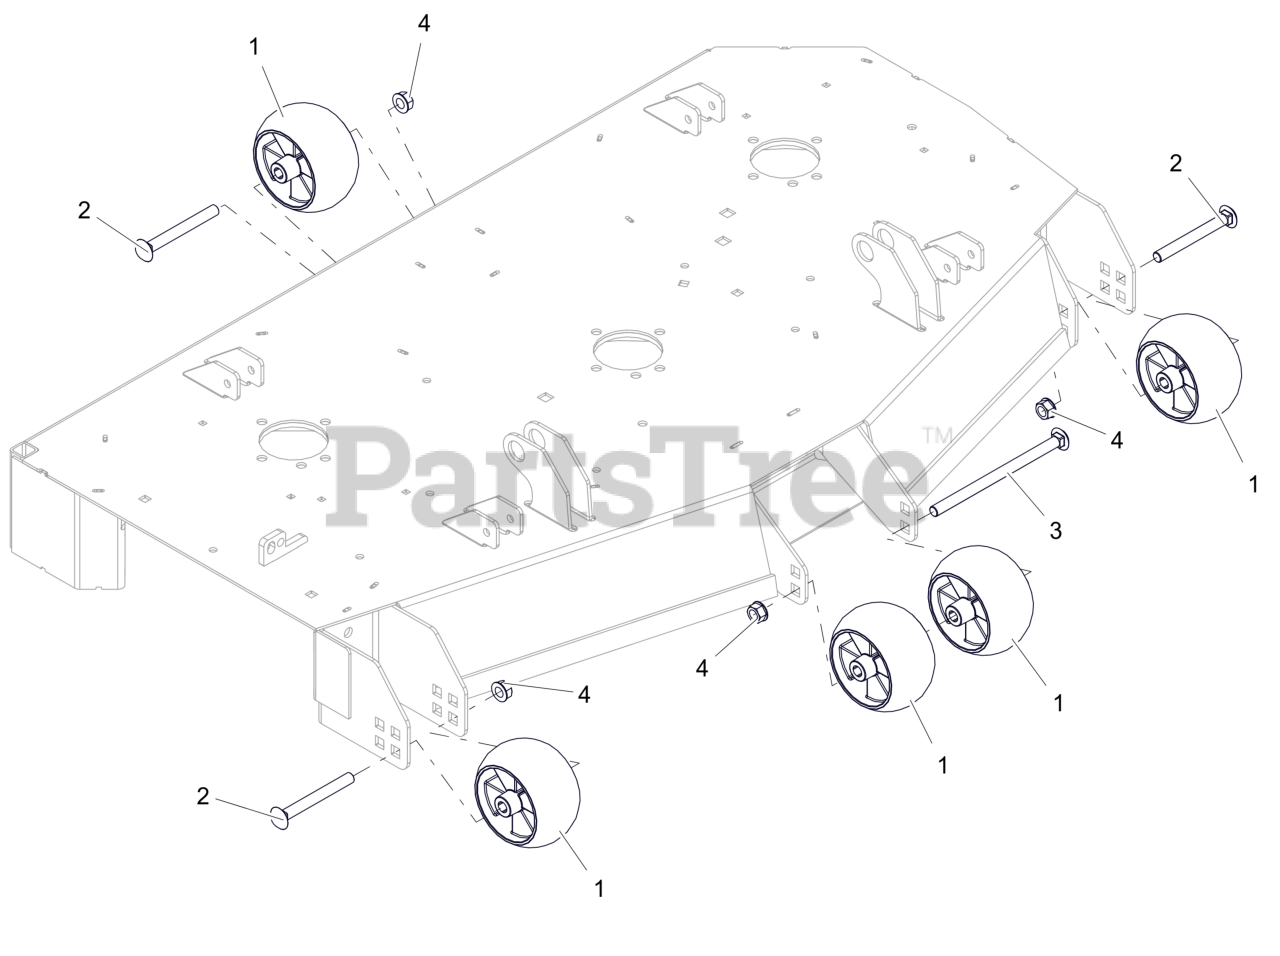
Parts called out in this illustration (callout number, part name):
1	WHEEL, ANTI SCALP - 5X3 CTR W/RIBS
2	BLT,RHSN .50-13X4.50 G5 ZCC
3	BTL,RHSN .500-13 X 8 G5 ZCC
4	NUT-LK-CTR-FLG .500-13 GG ZCC
